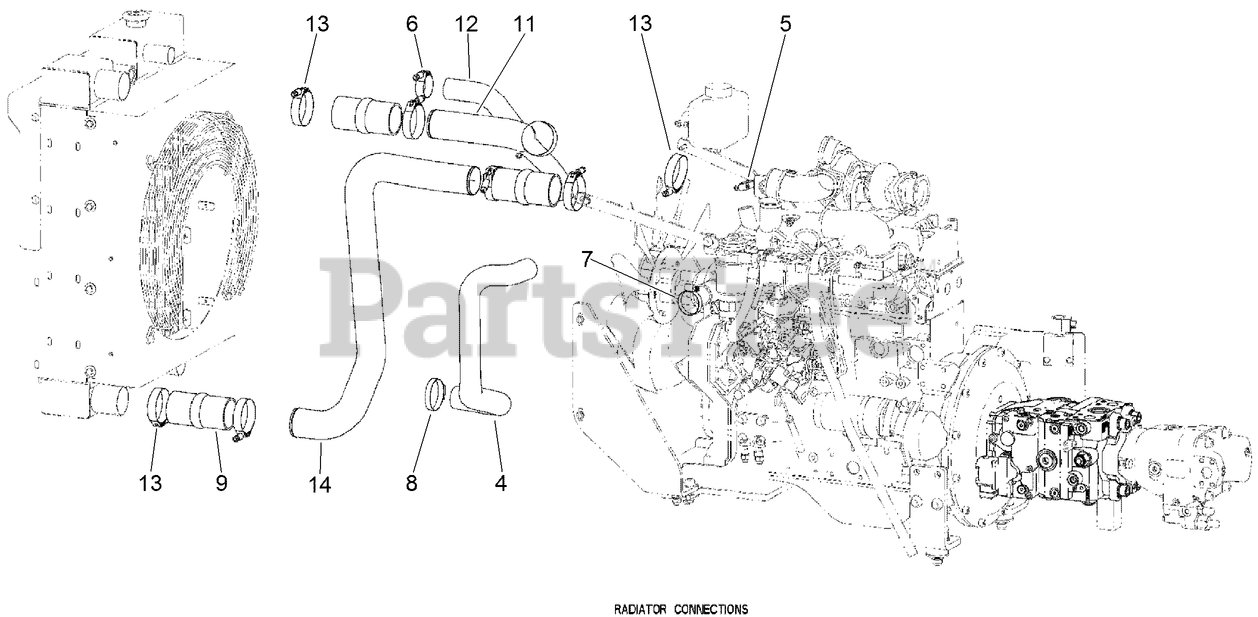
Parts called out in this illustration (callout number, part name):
4	HOSE - Lower Radiator, Molded
5	CLAMP - Hose Type F # 24
6	CLAMP-HOSE (T-BOLT)
7	CLAMP-Hose Type F #32
8	CLAMP - Hose Type F # 36
9	CONNECTOR - 2.5 Silicon Charge Air
11	CHARGED AIR - Upper Tube
12	HOSE - Upper Radiator
13	CLAMP - Constant Torque
14	CHARGED AIR - Lower Tube
